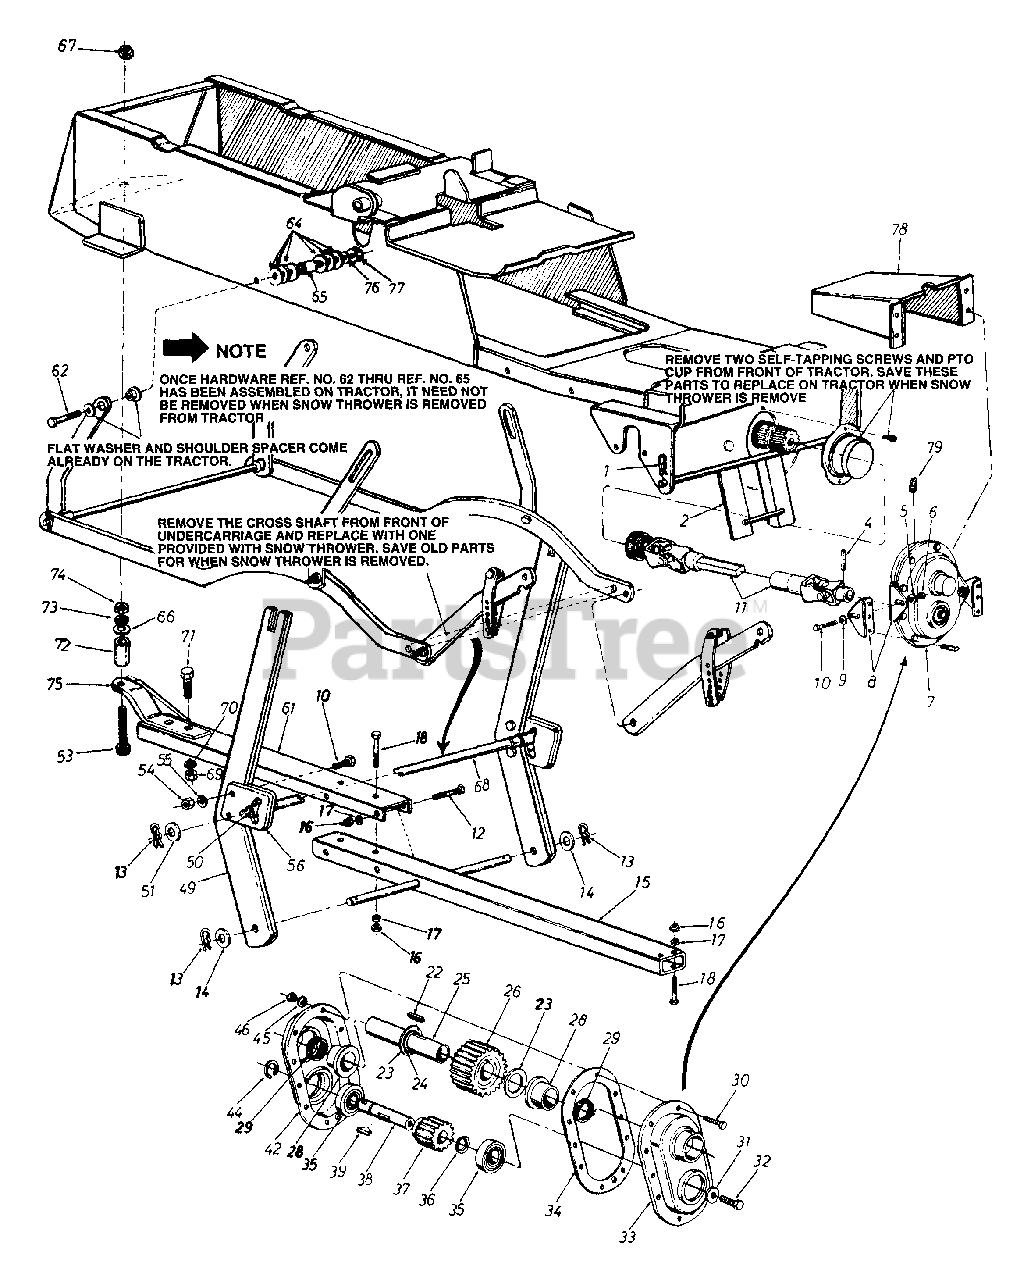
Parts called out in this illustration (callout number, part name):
1	Intern. Cotter Pin 3/4" Dia.
2	Guide Bracket Ass'y.
4	Spring Pin Spiral 5/16" Dia. x 2.5" Lg.
5	Bell-Wash. .341" I.D. x .88" O.D.
6	Hex Nut 5/16-18 Thd.
7	Gear Box Ass'y. Comp.
8	Gear Box Support Brkt.
9	Bell-Wash. .341" I.D. x .88" O.D.
10	Hex Scr. 5/26-18 x .75" Lg.
11	Universal Drive Shaft Ass'y.
12	Hex Scr. 3/8-24 x 4.50" Lg.
13	Hairpin Cotter
14	Fl-Wash. .62" I.D. x 1.12" O.D.
15	Lift Shaft Ass'y.
16	Hex Ins. Jam L-Nut 3/8-24 Thd.
17	L-Wash. 3/8" Scr.
18	Hex Scr. 3/8-24 x 2.75" Lg.
22	Fl-Wash. 1.31" I.D. x 2.00" O.D. x .060
24	Snap Ring for 1/25" Dia. Shaft
25	Gear Shaft 1.25" Dia. x 6.0" Lg.
26	28 Teeth Spur Gear
28	Flange Brg. 1.25" I.D. x 1.75" O.D.
29	Oil Seal 1.25" I.D. x 1.75" O.D. x .26
30	Hex Scr. 1/4-28 x .88" Lg.
31	Fl-Wash..40" I.D. x 1.25" O.D. x .160
32	Hex L-Scr. 3/8-24 x 1.00" Lg.
33	Compl. Gear Hsg. Half - L.H.
35	Ball Brg. 1.00" I.D. x 2.00" O.D.
36	Fl-Wash. 1.03" I.D. x 1.63" x .090
37	15 Teeth Spur Gear
39	Woodruff Key 1/4" x 3/4" Dia.
42	Compl. Gear Hsg. Half - R.H.
44	Snap Ring for 1.00" Dia. Shaft
45	Spring Wash. 1/4" I.D.
46	Hex Nut 1/4-28 Thd.
51	Fl-Wash. .62" I.D. x 1.12" O.D.
53	Hex Bolt 5/8-18 x 4.00" Lg.
54	Hex Nut 5/16-18 Thd.
55	L-Wash. 5/16" Scr.
61	Lift Bracket
62	Hex Scr. 3/8-24 x 2.50"
64	Fl-Wash. .375" I.D. x 1.00" O.D. x .135"
65	Spacer .275" l.D. x .625" O.D. x .440
66	Fl-Wash. .62" I.D. x 1.12" O.D.
67	Hex Jam L-Nut 5/8-18 Thd.
68	Cross Shaft Ass'y.
69	Hex Nut 1/2-13 Thd.
70	L-Wash. 1/2" Scr.
71	Hex Scr. 1/2-13 x 1.25"
73	L-Wash. 5/8" Scr.
74	Hex Jam Nut 5/8-18 Thd.
77	Hex Nut 3/8-24 Thd.
78	Drive Shaft Cover
79	Grease Fitting
